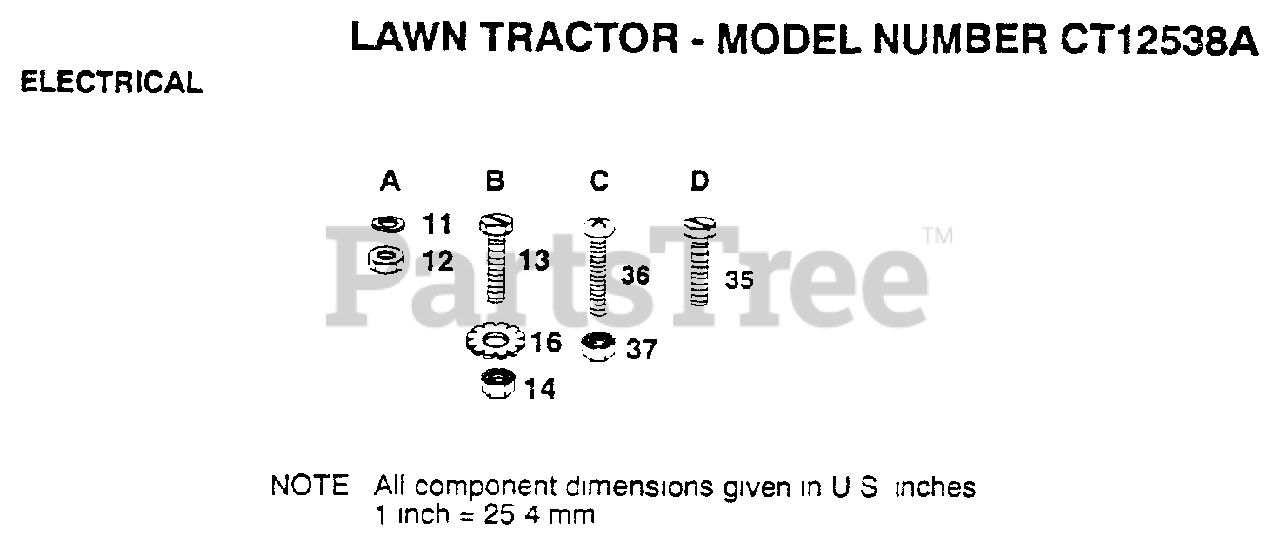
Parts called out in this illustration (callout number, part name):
12	NUT
13	BOLT
14	NUT
35	SCREW
37	"NUT,KEPS"
